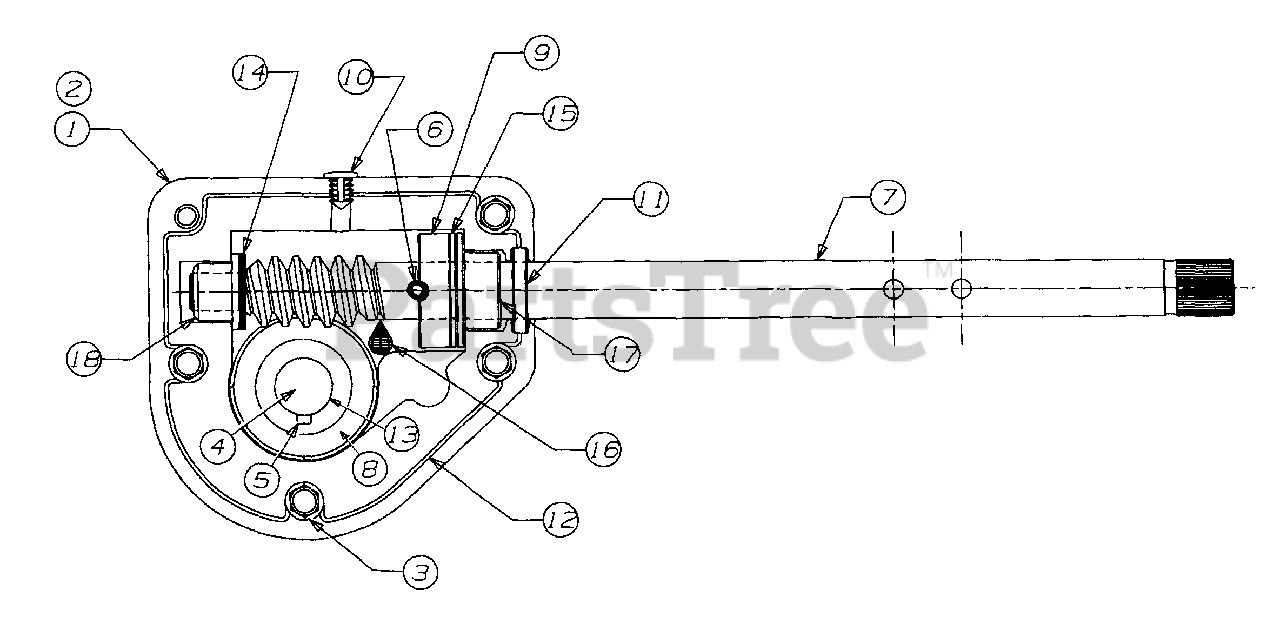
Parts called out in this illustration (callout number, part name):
1	Housing R.H.
2	Housing L.H.
3	Screw - Hex
4	Axle 24" Housing
5	Key - Hi-Pro (24" & 26")
6	Pin - Spiral
7	Work - Shaft
8	Gear - Worm 20T
9	Collar - Thrust
10	Plug - Plastic
11	Seal - Oil
12	Locktite 5699 - Ultra Grey Sealant
13	Washer - Flat
14	Washer - Flat
15	Washer - Flat
16	Grease 1.5 oz.
17	Bearing - Flange
18	Bearing - Flange
